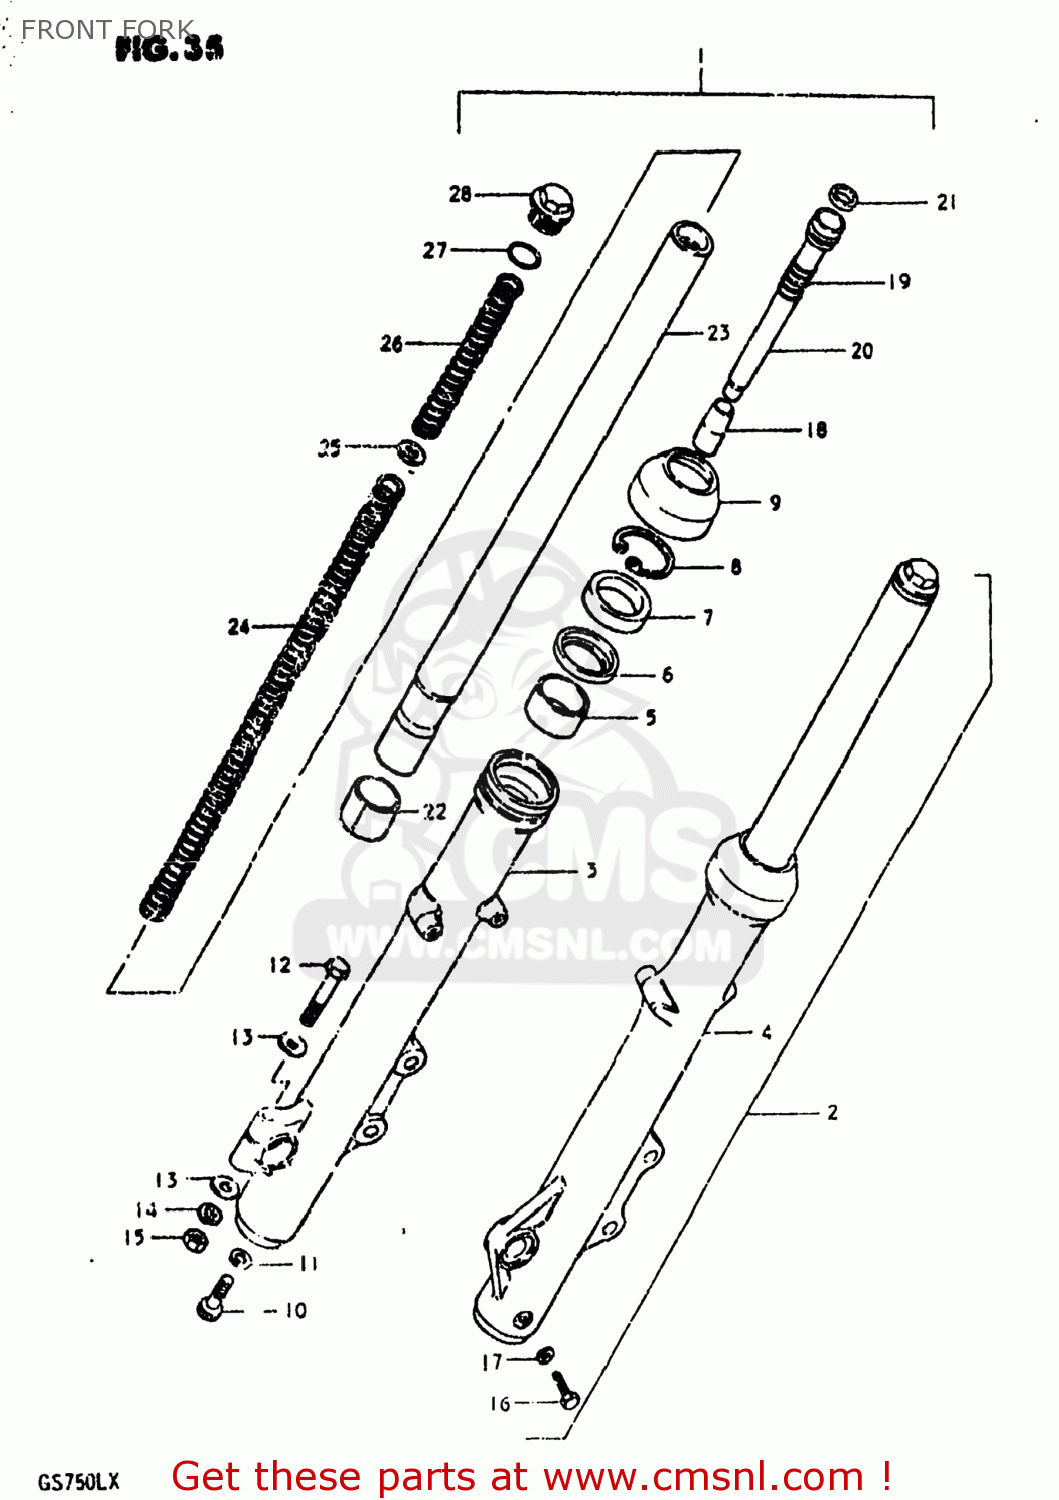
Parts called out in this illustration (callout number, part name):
1	DAMPER ASSEMBLY,RIGHT
2	DAMPER ASSEMBLY,LEFT
3	TUBE,FORK,OUTER,RIGHT
4	TUBE,FORK,LEFT,OUTER
5	BUSH,GUIDE
6	SPACER,SEAL
7	OIL SEAL,FRONT FORK
8	CIRCLIP,FORK OIL SEAL
9	BOOT
10	BOLT(8X27)
11	GASKET (NAS)
12	BOLT 8X50
13	WASHER
14	LOCK WASHER
15	NUT
16	BOLT(6X8)
17	GASKET,DRAIN,PLUG (NAS)
18	PIECE,OIL LOCK
19	SPRING,FORK REBOUND
20	CYLINDER,FRONT FORK
21	RING
22	PISTON
23	TUBE,FORK,INNER
24	SPRING,FRONT FORK MAIN,LOWER
25	WASHER,SPRING
26	SPRING,FRONT FORK,UPPER
27	O-RING
28	CAP,INNER TUBE
